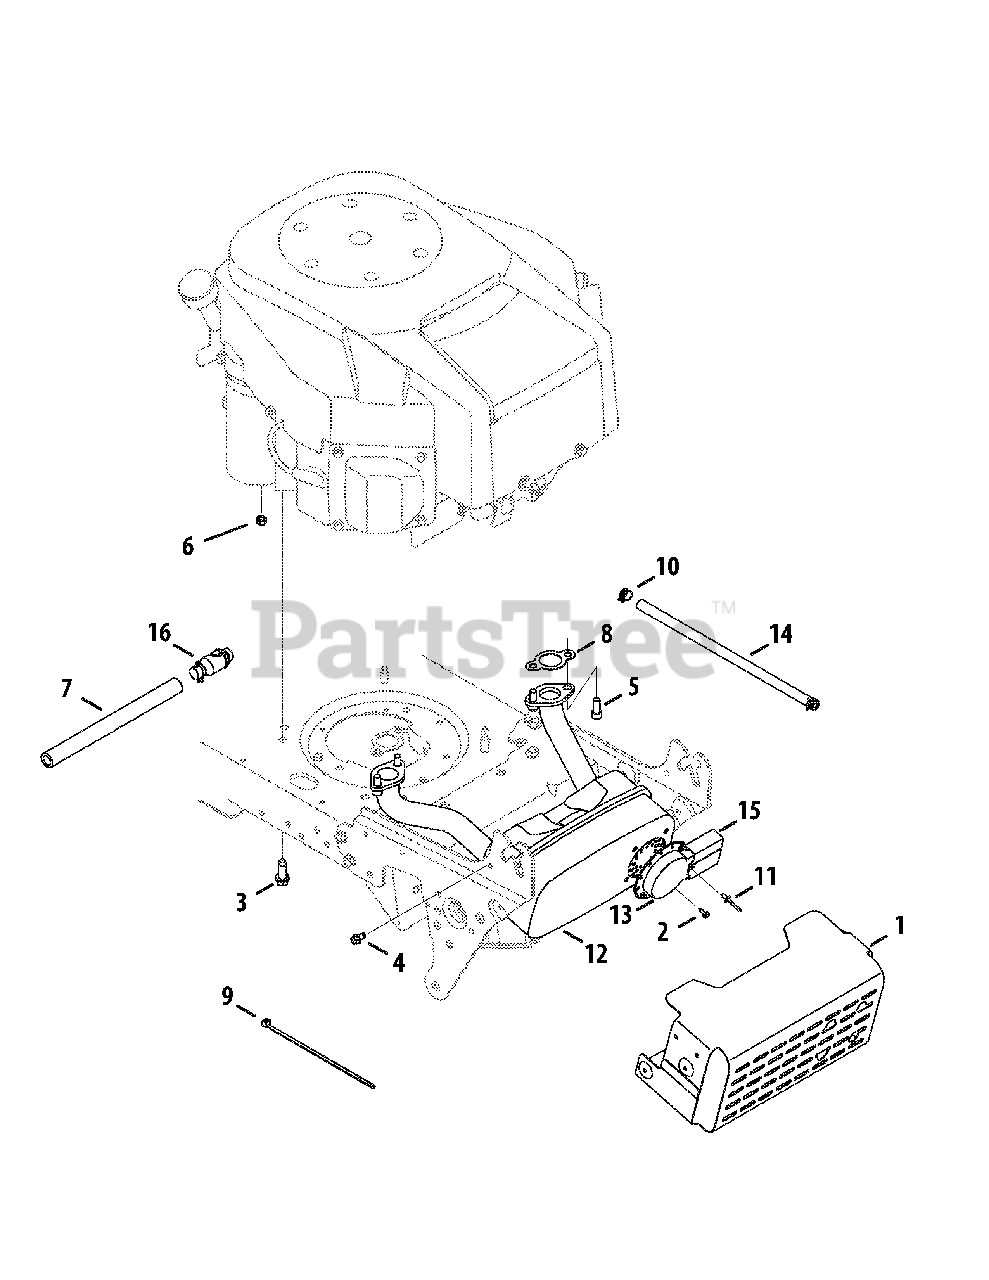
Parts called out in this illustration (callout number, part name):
1	Shield Ass’y, Muffler
2	Screw, Ab, #8-18, 0.500,
3	Screw, Self-tapping, 3/8-16, 1.000,
4	Screw, Self-tapping, 1/4-20, 0.500,
5	Screw, Socket Head, 5/16-18, .750
6	Nut, Sems, 1/4-20
7	Hose, Extension, Oil Drain
8	Gasket, Exhaust
9	Cable, Tie, 3/16 x .05 x 7.4
10	Clamp, Hose, .490 Dia.
11	Rivet, Pop, .188 Dia x .300
12	Muffler, Kohler Twin
13	Deflector, Muffler
14	Hose, Fuel, Low Permeation, 1/4
15	Deflector, Muffler, Long
